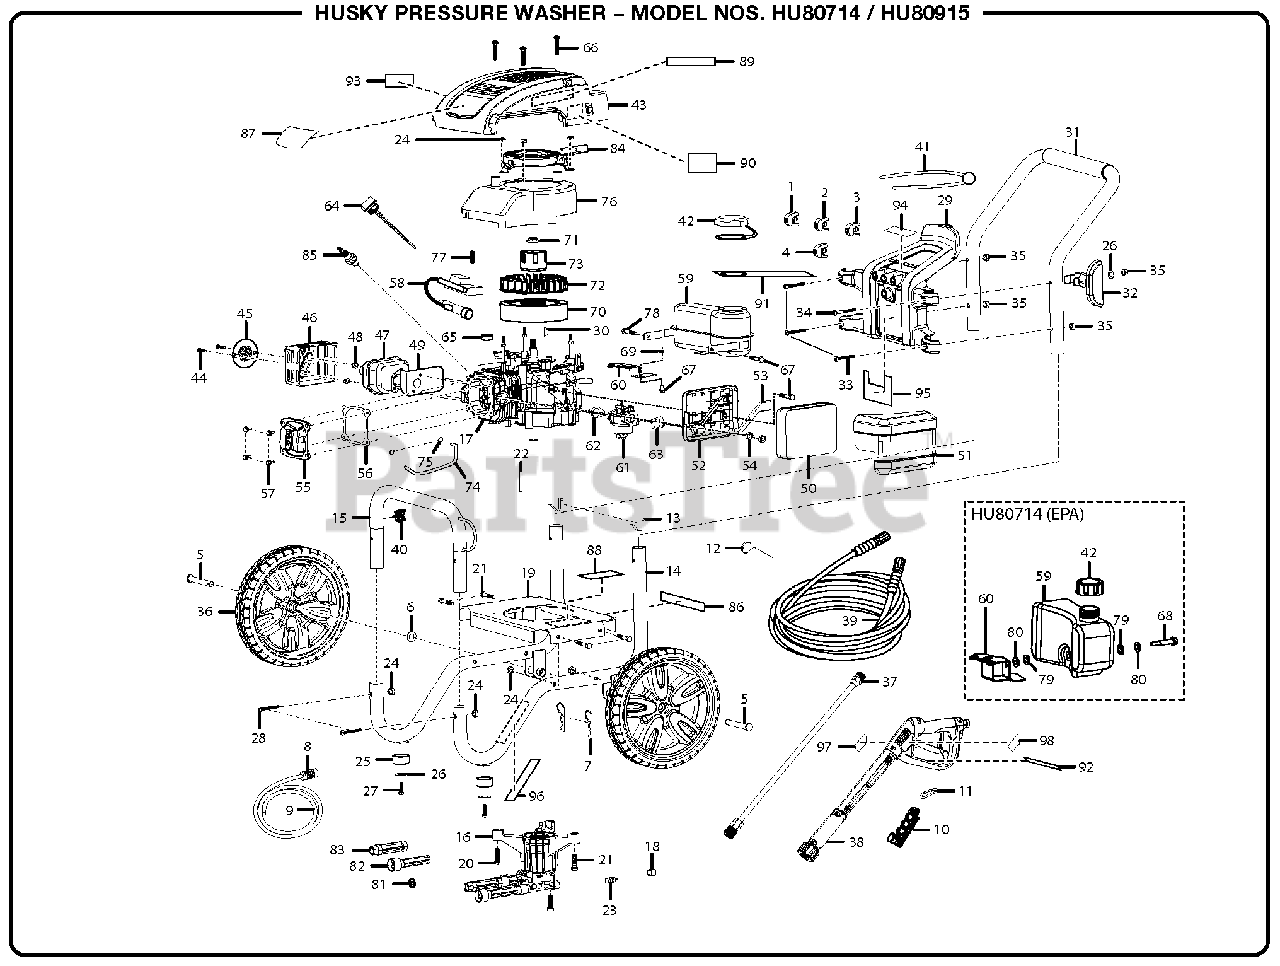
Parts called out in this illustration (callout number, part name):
1	0deg Nozzle
2	15deg Nozzle
3	25deg Nozzle
4	Detergent Nozzle
5	Axle
6	Washer (1/2 in)
7	Hitch Pin
9	Injection Hose
10	Storage Holder (4 Nozzle)
11	Spring Clip
12	Nozzle Cleaning Tool
13	Lock Button w/Spring Clip
14	Main Frame Assembly
15	Front Frame
16	Pump
17	Engine (173cc EPA)
18	TRV Spout
19	Engine Plate
20	Bolt (M8 x 66 mm)
21	Bolt (M8 x 50 mm)
22	Output Shaft Key
23	Thermal Release Valve
24	Lock Nut (M8)
26	Washer (1/4 in)
27	Bolt (1/4-20 x 1 in, Hex Hd)
28	Bolt (M8 x 45 mm)
29	Hose and Nozzle Holder
30	Flywheel Key (Woodruff Key)
31	Handle Assembly
32	Wand Holder
33	Screw (1/4-20 x 185 in, Torx)
34	Screw (1/4-20 x 227 in, Torx)
35	Lock Nut (1/4-20)
36	Wheel (12 in. x 2 in.)
37	Spray Wand
38	Trigger Handle Assembly
39	High Pressure Hose
40	Injection Hose Holder
41	Bungee Cord and Bead Assembly
42	Fuel Cap
43	Shroud Assembly w/Switch
44	Screw (M6 x 12 mm)
45	Spark Screen
46	Muffler Cover
47	Muffler
48	Hex Nut (M6)
49	Heat Shield
50	Air Filter
51	Air Filter Cover
52	Air Filter Bracket
53	Air Filter Cleaner Breather Cover
54	Hex Nut (M6)
55	Valve Cover
56	Valve Cover Gasket
57	Bolt (M6 x 12 mm)
58	Ignition Module
59	Fuel Tank Assembly
60	Fuel Tank Bracket
61	Carburetor
62	Carburetor Gasket
63	Air Cleaner Gasket
64	Oil Dipstick
65	Spacer Block
66	Screw (M6 x 20 mm)
67	Screw (M6 x 12 mm)
68	Bolt (Fuel Tank Bracket)
69	Hex Nut (Tank Bracket)
71	Flywheel Nut
73	Starter Pulley
74	Fuel line
75	Fuel Line Clip
76	Inner Blower Housing Assembly
77	Screw (M6 x 25 mm)
78	Screw (M6 x 40 mm)
81	Filter Screen
82	Inlet Tube
83	Outlet Tube
84	Recoil Starter Assembly
85	Spark Plug (Champion 2415)
86	Data Label
87	Engine Shroud Label
88	Warning Label
89	Engine Quick Start Label
90	Choke Label
91	Engine Oil Fill (Hang Tag)
92	Wand Label (Max Rating)
93	Hot Muffler Label
94	Nozzle Label
95	Performance Label
96	Pump Quick Start Label
97	Trigger Handle Warning Label
98	Trigger Handle Logo Label
